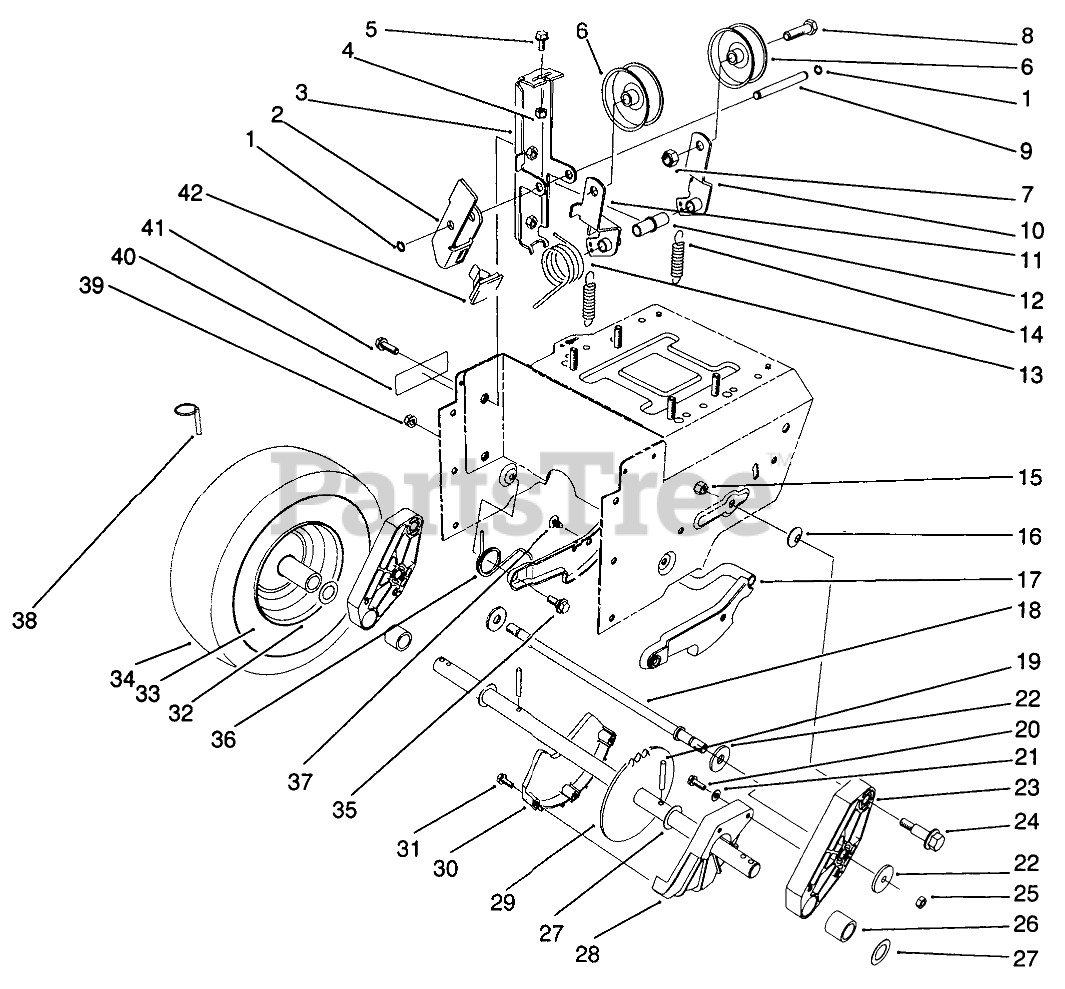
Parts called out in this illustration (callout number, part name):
1	RING-RETAINING
2	ARM-BRAKE
3	IDLER ARM BRACKET ASM
4	NUT-LOCK, NI
5	SCREW-HHF
6	PULLEY-IDLER
7	NUT-LOCK, NI
8	SCREW-HH
9	PIN-IDLER
10	ARM-IDLER, TRACTION
11	ARM-IDLER, IMPELLER
12	BUSHING-IDLER
13	TORSION SPRING
14	SPRING-EXTENSION
15	NUT-LOCK, NI
16	WASHER-SPRING
17	Latch-Arm
18	ROD-LATCH
19	PIN-ROLL, SLOTTED
20	SCREW-HWH
21	WASHER-FLAT
22	WASHER-SUPPORT
23	Pivot Arm Assembly (Incl. Ref. #26)
24	BOLT-SHOULDER
25	NUT-LOCK, NI
26	BUSHING-AXLE
27	WASHER-THRUST
28	GUARD-CHAIN, LH
30	GUARD-CHAIN, RH
31	Screw
32	RIM-WHEEL
33	INNER TUBE
35	SCREW-SHOULDER
36	SPRING-LATCH, TORSION
37	FASTENER-PANEL
38	PIN-LYNCH
39	NUT-LOCK, NI
40	DECAL-WARNING
41	SCREW-HHF
42	PAD-BRAKE
